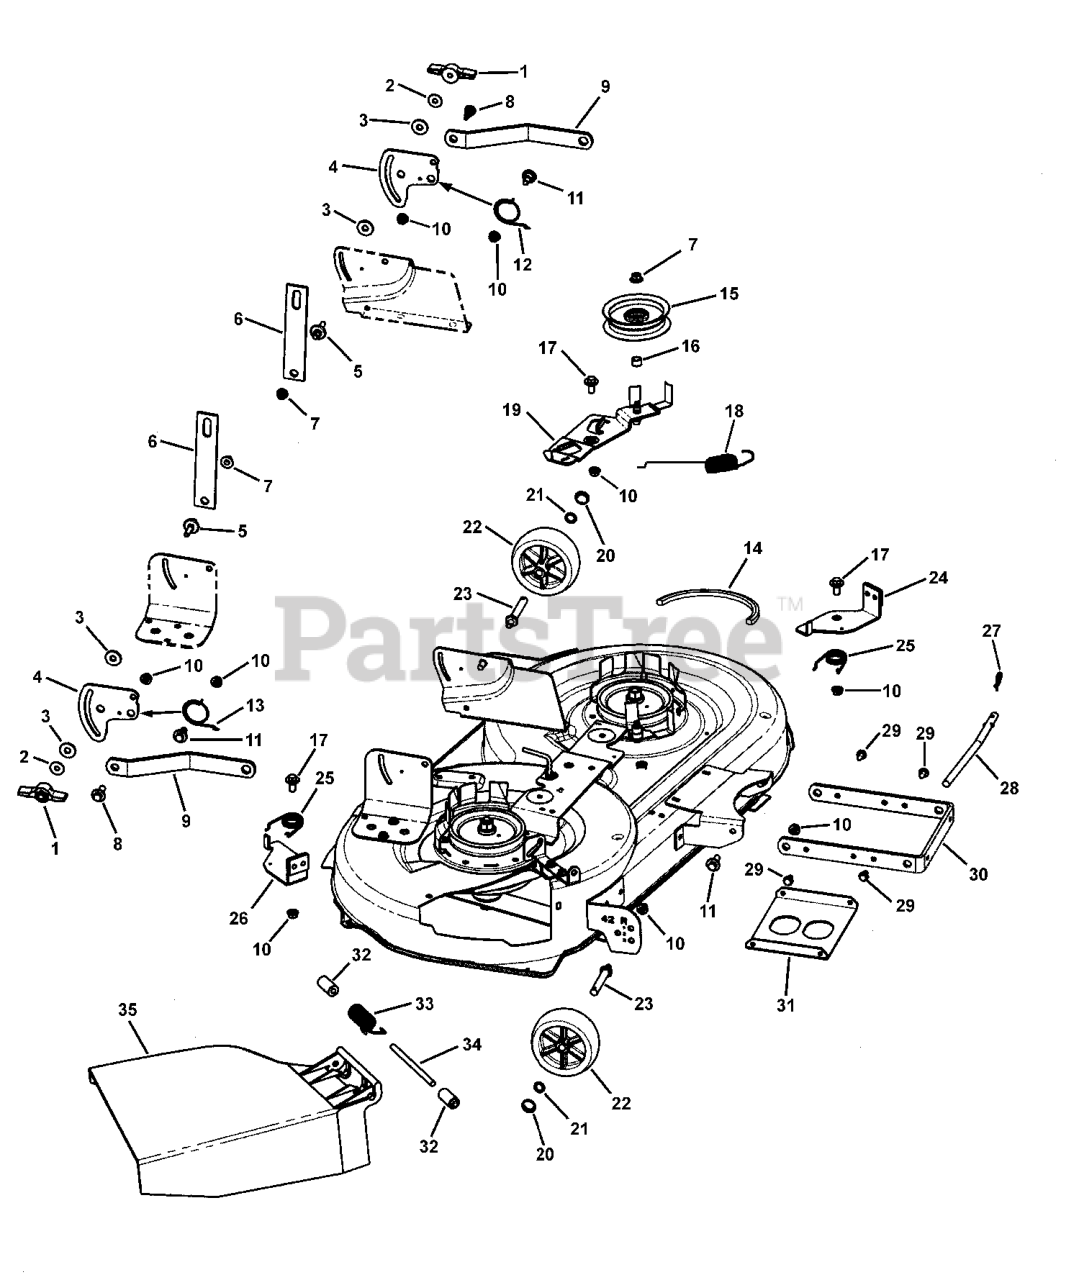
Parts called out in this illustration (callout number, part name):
1	KNOB (5/16-18 nut enclosed)
2	WASHER FLAT, 1.0 X .328 X 16GA
3	FRICTION PAD
4	PLATE SUSPENSION
5	PIN - HANGER 3/8-16 X 1.25
6	LINK - LIFT (LT)
7	NUT FLANGE, 3/8-16 ZINC PLATED
8	SHOULDER BOLT, 3/8-16 X .600OD X.95L
9	BRACKET SUSPENSION
10	NUT, HEX FLANGE, 3/8-16 NC
11	SHOULDER BOLT, 3/8-16X1.06
12	SPRING, TORSION RH
13	SPRING, TORSION RH
14	BELT, V MOWER DRIVE 42" (HA Sect.; 89.19 E.L.)
15	PULLEY BACKSIDE IDLER, 4.0 OD
16	SPACER, 1/2" TO 17MM
17	SHOULDER BOLT, 0.75 X 0.60 X 3/8-16
18	SPRING EXTENSION, 9.43L X 0.62D
19	ASSY-IDLER ARM, 42"
20	CLIP - HAIR PIN
21	WASHER, FLAT, .81 X .550 X 16GA
22	WHEEL GAGE
23	BOLT, Gauge Wheel
24	ASSY-BRAKE L.H.
25	SPRING, TORSION BRAKE
26	ASSY-BRAKE R.H.
27	HAIR PIN, .56D-.092T
28	ROD HANGER
29	CAPSCREW, 5/16-18
30	BRKT SUSPENSION FRONT
31	STIFFENER
32	CAP, PUSH ON
33	SPRING, Torsion
34	ROD, Deflector
35	ASSY, DEFLECTOR
